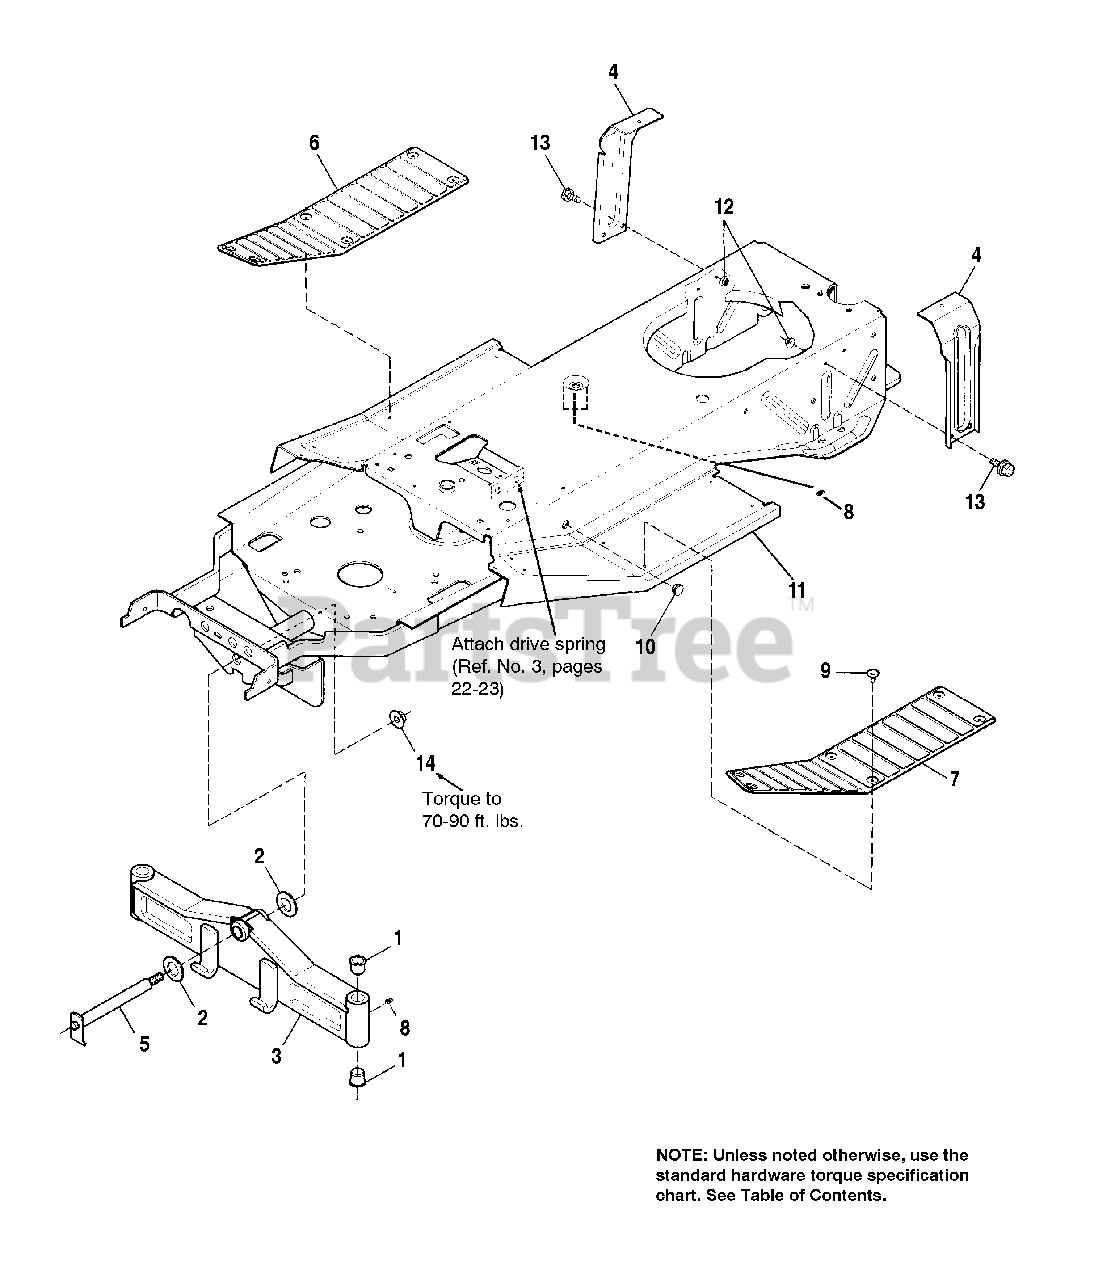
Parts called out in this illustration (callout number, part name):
2	WASHER
3	AXLE ASSY., Front
4	SUPPORT, Seat
5	AXLE PIVOT ASSY.
6	PAD, Footrest, RH
7	PAD, Footrest, LH
8	GREASE, Fitting
9	FASTENER, Panel
11	FRAME ASSY.
12	NUT, Hex, ESNA, Lock, 3/8-16
13	CAPSCREW, Hex, Flange, Whizlock, 3/8-16 x 1
14	NUT, Hex, Full, Lock, 3/4-16
